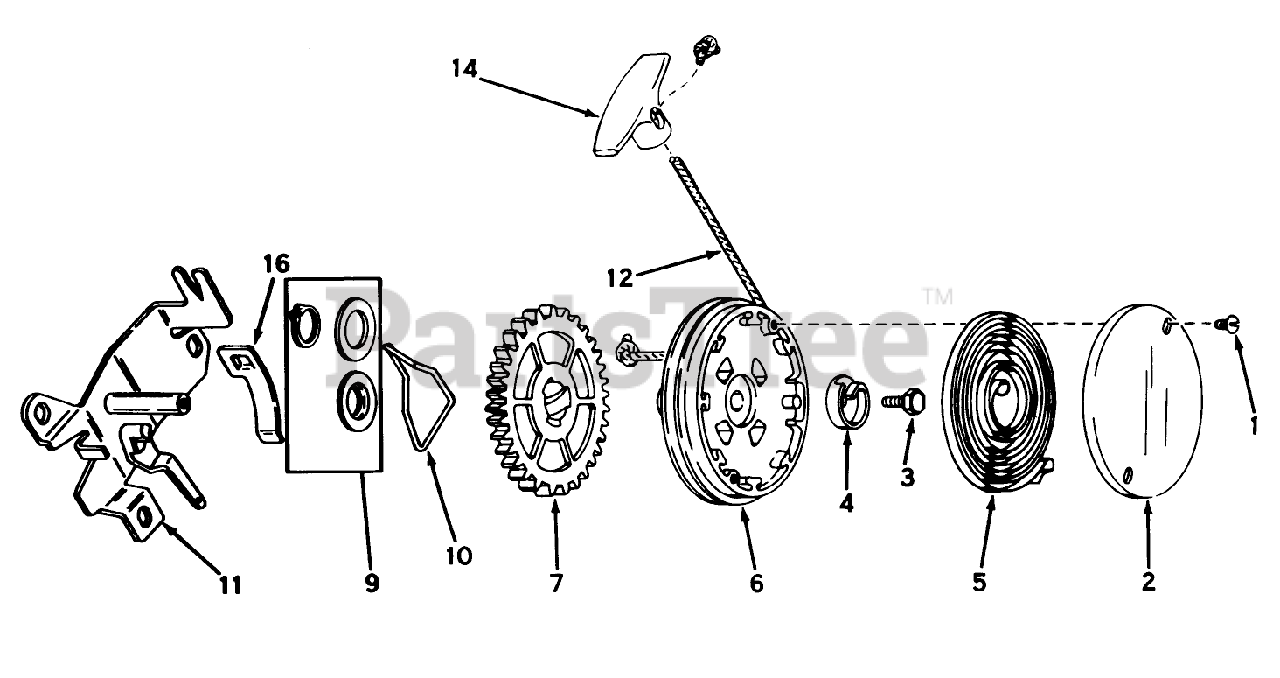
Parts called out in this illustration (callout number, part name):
1	Screw
2	Cover, Spring
3	Screw, Hex Washer Head
4	Hub Spring
5	Spring, Rewind
6	Pulley Assy. (Incl. No. 9)
9	Kit, Thrust Wash. Snap Rg.
10	Brake
11	Bracket Assy., Mounting
12	Rope-Starter
14	Handle-Starter
16	Clip Rope
